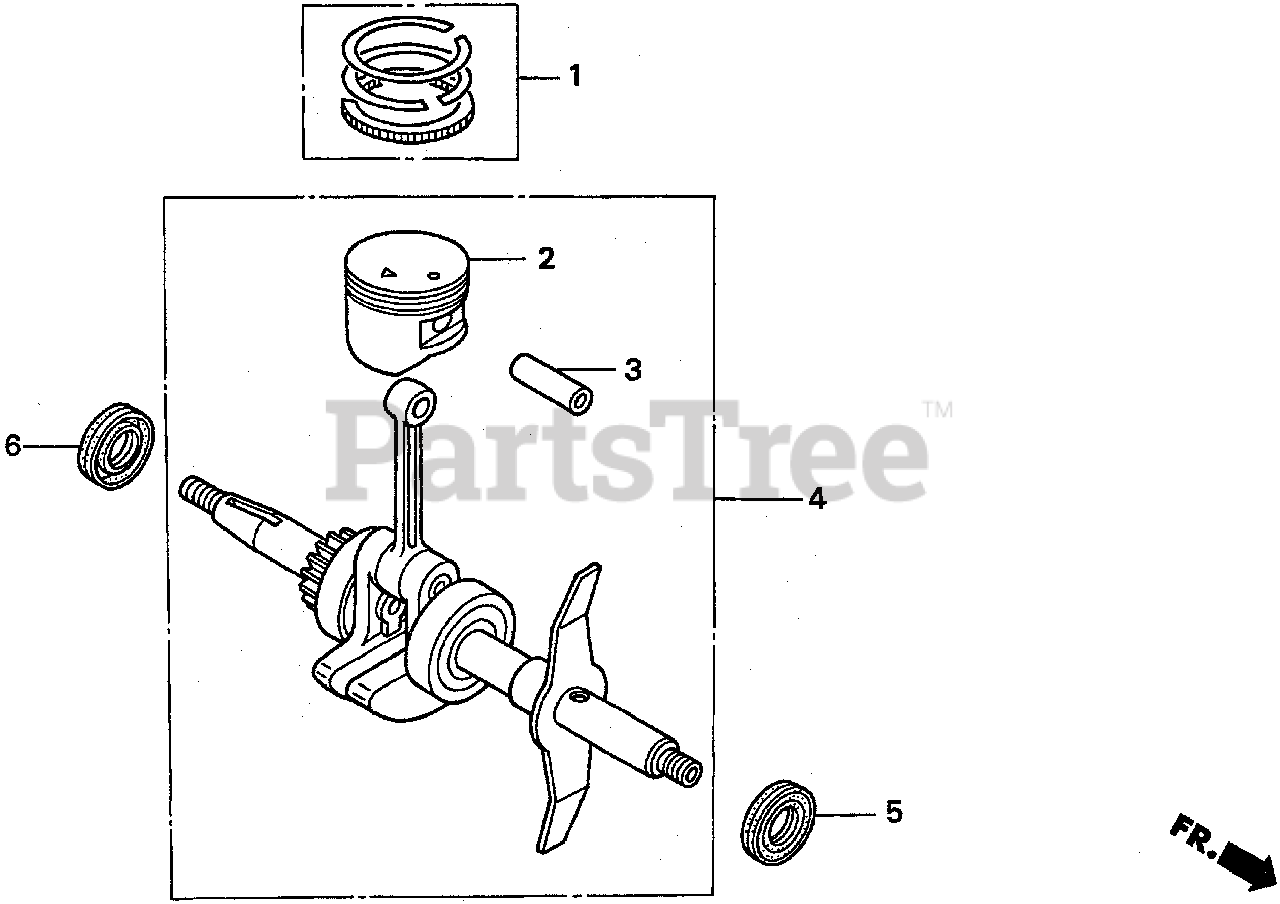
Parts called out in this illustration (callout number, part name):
1	RING SET, PISTON
2	PISTON
3	PIN, PISTON
4	CRANKSHAFT COMP.
5	OIL SEAL (12X25X6)
6	OIL SEAL (15X25X6)
